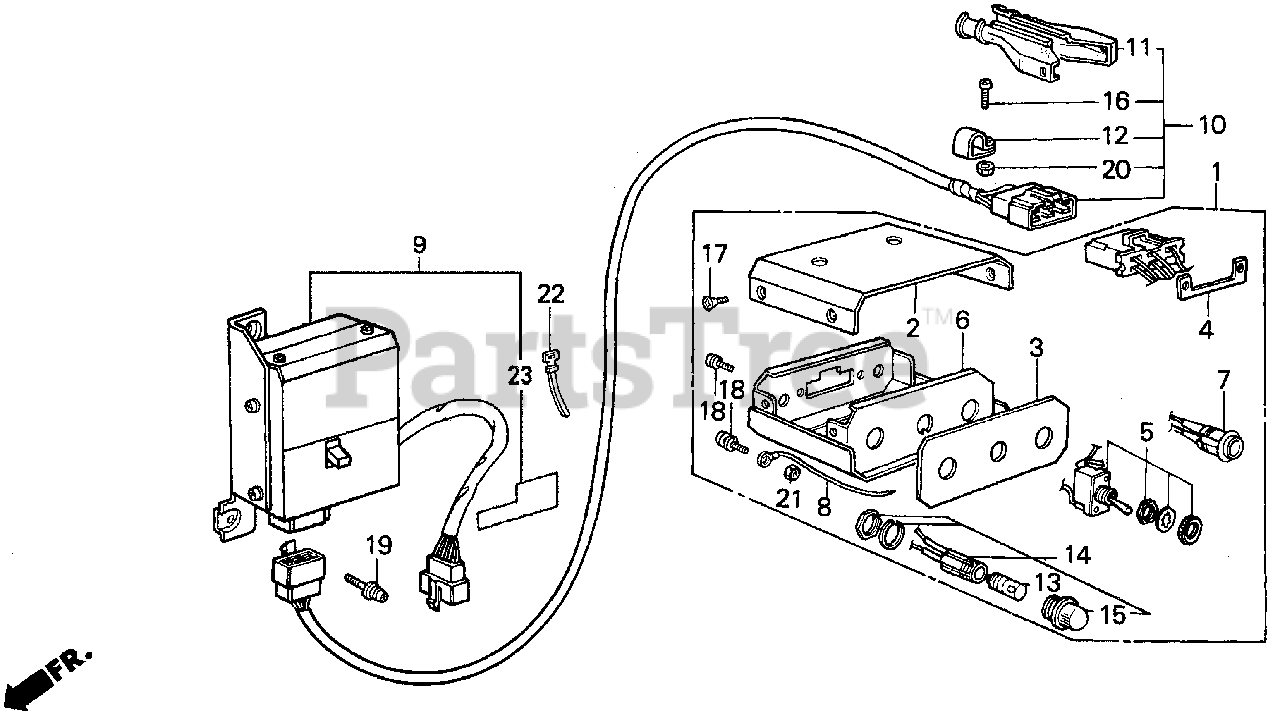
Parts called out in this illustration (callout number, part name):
1	BOX ASSY., SWITCH (NOT AVAILABLE)
2	COVER (UPPER) Use from Frame SN 1001725.
3	PLATE, SWITCH & INDICATOR Use from Frame SN 1001725.
4	PLATE, CONNECTOR SETTING
5	SWITCH, TOGGLE
6	PANEL, CONTROL *R8* (BRIGHT RED) Use up to Frame SN 1120559.
7	SWITCH, PUSH
8	WIRE, GROUND
9	BOX ASSY., RELAY
10	CABLE, REMOTE CONTROL (10MM)
11	COVER, CONNECTOR
12	BAND
13	BULB, WEDGE BASE (12V/2W) Use from Frame SN 1001725.
14	SOCKET ASSY., LAMP (GREEN) Use from Frame SN 1001725.
15	LENS (GREEN) Use from Frame SN 1001725.
16	SCREW, PAN (3X12)
17	SCREW, FLAT (4X8) Use from Frame SN 1001725.
18	SCREW-WASHER (4X12)
19	SCREW-WASHER (6X25)
20	NUT, HEX. (3MM)
21	NUT, HEX. (4MM)
22	BAND B1, CABLE
23	MARK, REMOTE CONTROL
